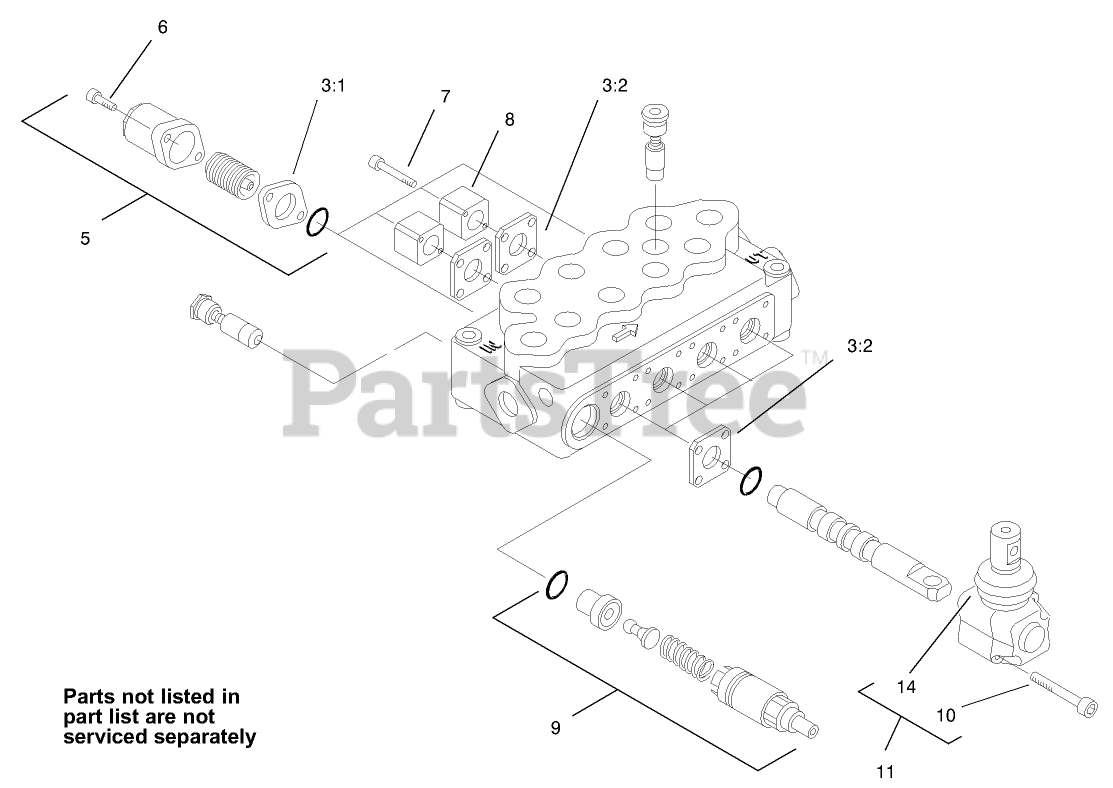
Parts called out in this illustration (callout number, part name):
3	SEAL KIT
3:1	GASKET
3:2	GASKET
5	HIGH FORCE SPRING KIT
6	SCREW-CAP, END
8	BLOCK-MOUNT, SWITCH
9	VALVE-RELIEF
11	OPERATOR ASM
